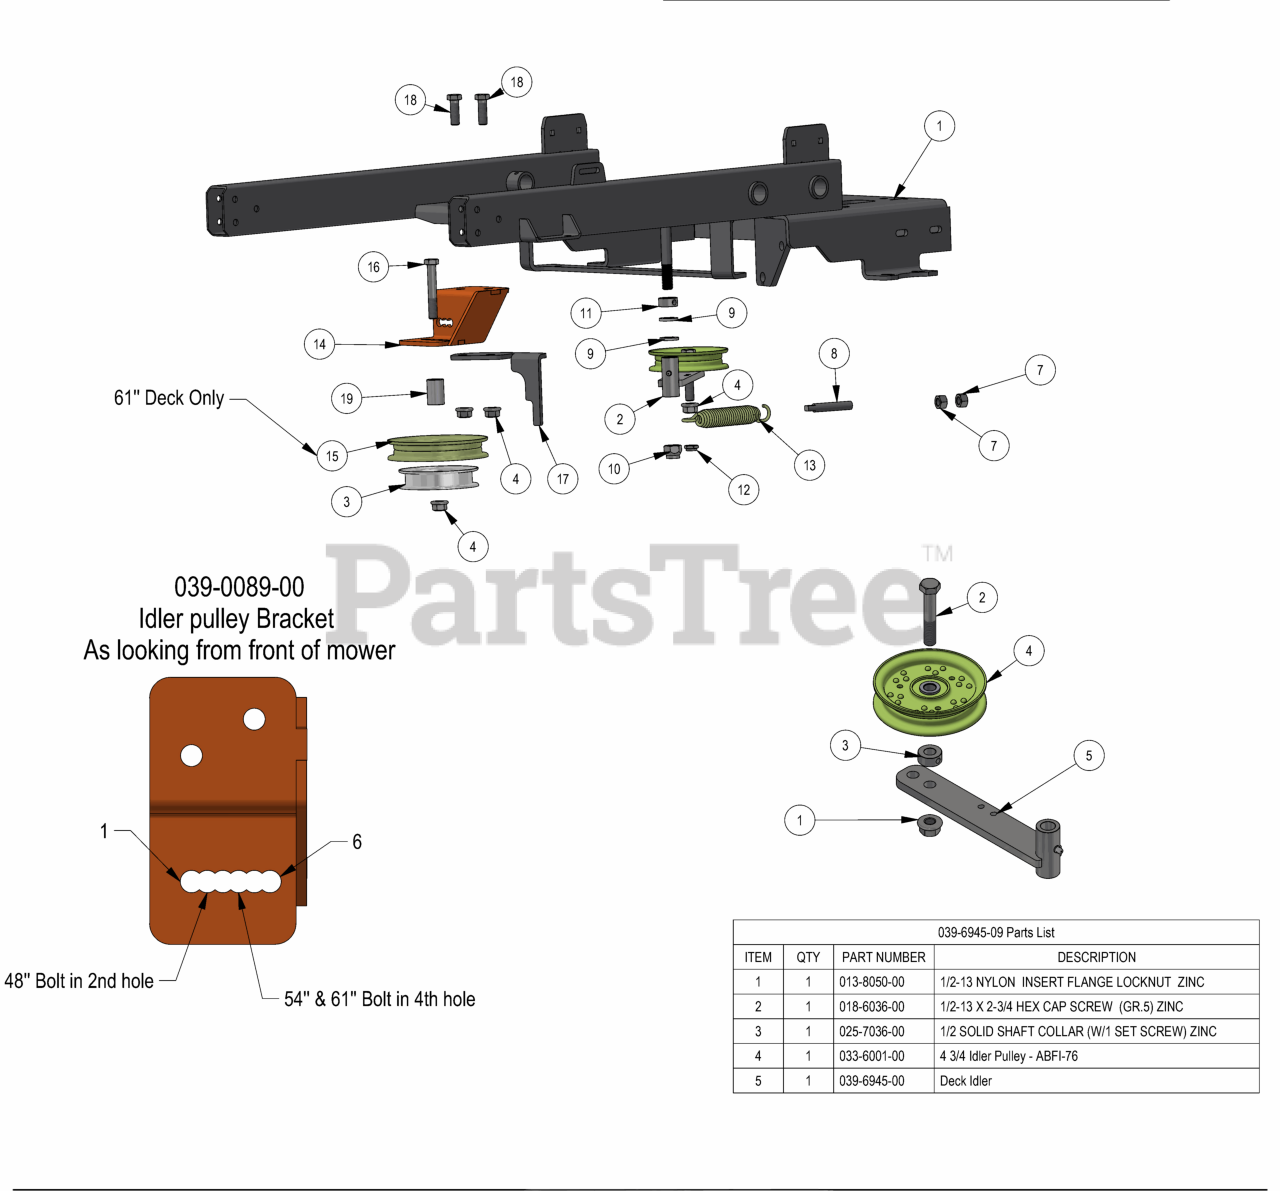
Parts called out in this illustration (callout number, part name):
1	2019 Stand On Frame
2	Deck Idler
3	4 3/4 Idler Pulley
4	1/2-13 NYLON INSERT FLANGE LOCKNUT ZINC
5	1/2-13 X 2-3/4 HEX CAP SCREW (GR.5) ZINC
6	1/2 SOLID SHAFT COLLAR (W/1 SET SCREW) ZINC
7	1/2-13 HEX NUT ZINC
8	All Thread
9	.635 ID X 1.120 OD X .140 THICK FLAT WASHER NYLON
10	5/8-11 NYLON INSERT LOCKNUT ZINC
11	5/8 SOLID SHAFT COLLAR (W/1 SET SCREW) ZINC
12	1/2-13 NYLON INSERT JAM LOCKNUT ZINC
13	Deck Idler Spring
14	Idler Pulley Bracket Weldment 2019 Stand On
15	5-3/4 Idler Pulley-Capitol Stampings
16	1/2-13 X 3-1/4 HEX CAP SCREW (GR.5) ZINC
17	2019 Stand On Clutch Stop Bracket
18	1/2-13 X 1-1/2 HEX CAP SCREW (GR.5) ZINC
19	.502 ID X .750 OD X 1.500 Long Spacer
